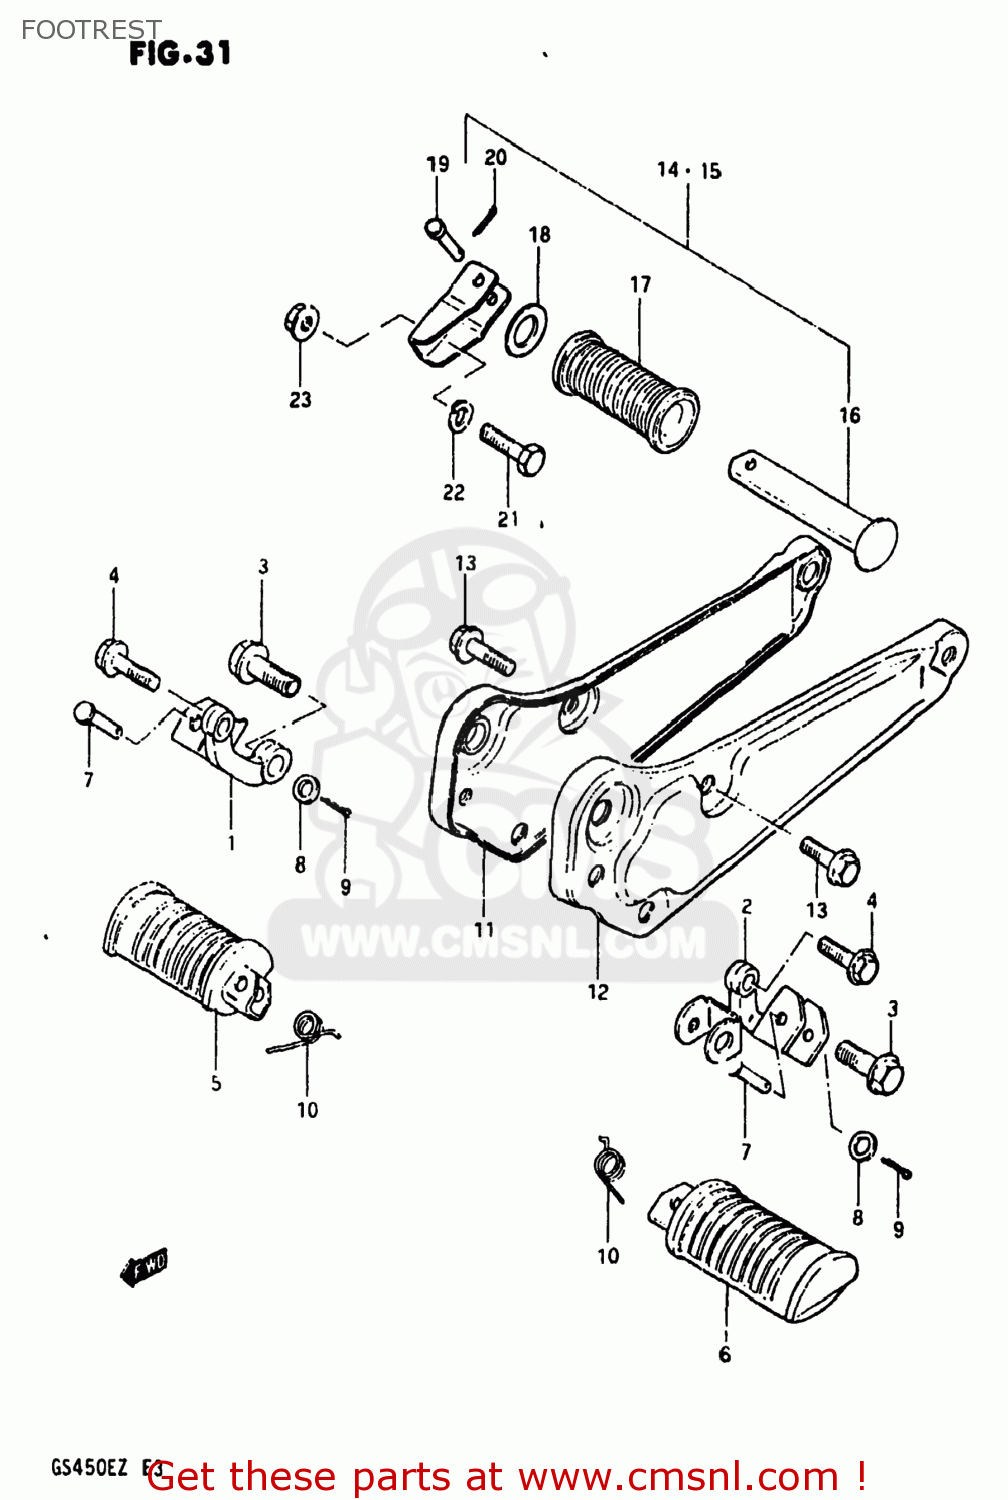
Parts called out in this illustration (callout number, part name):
1	BAR,FRONT FOOTREST,RIGHT
2	BAR,FRONT FOOTREST,LEFT
3	BOLT
4	BOLT
5	RUBBER,FRONT FOOTREST
6	FOOTREST
7	PIN
8	WASHER
9	PIN
10	SPRING
11	BRACKET
12	BRACKET
13	BOLT
14	FOOTREST ASSEMBLY,REAR
15	FOOTREST ASSEMBLY,PILLION
16	BAR,PILLION FOOTREST
17	RUBBER,PILLION FOOTREST
18	WASHER (19.5X32X2)
19	PIN
20	PIN
21	BOLT,M10X1.25X
22	LOCK WASHER
23	NUT
